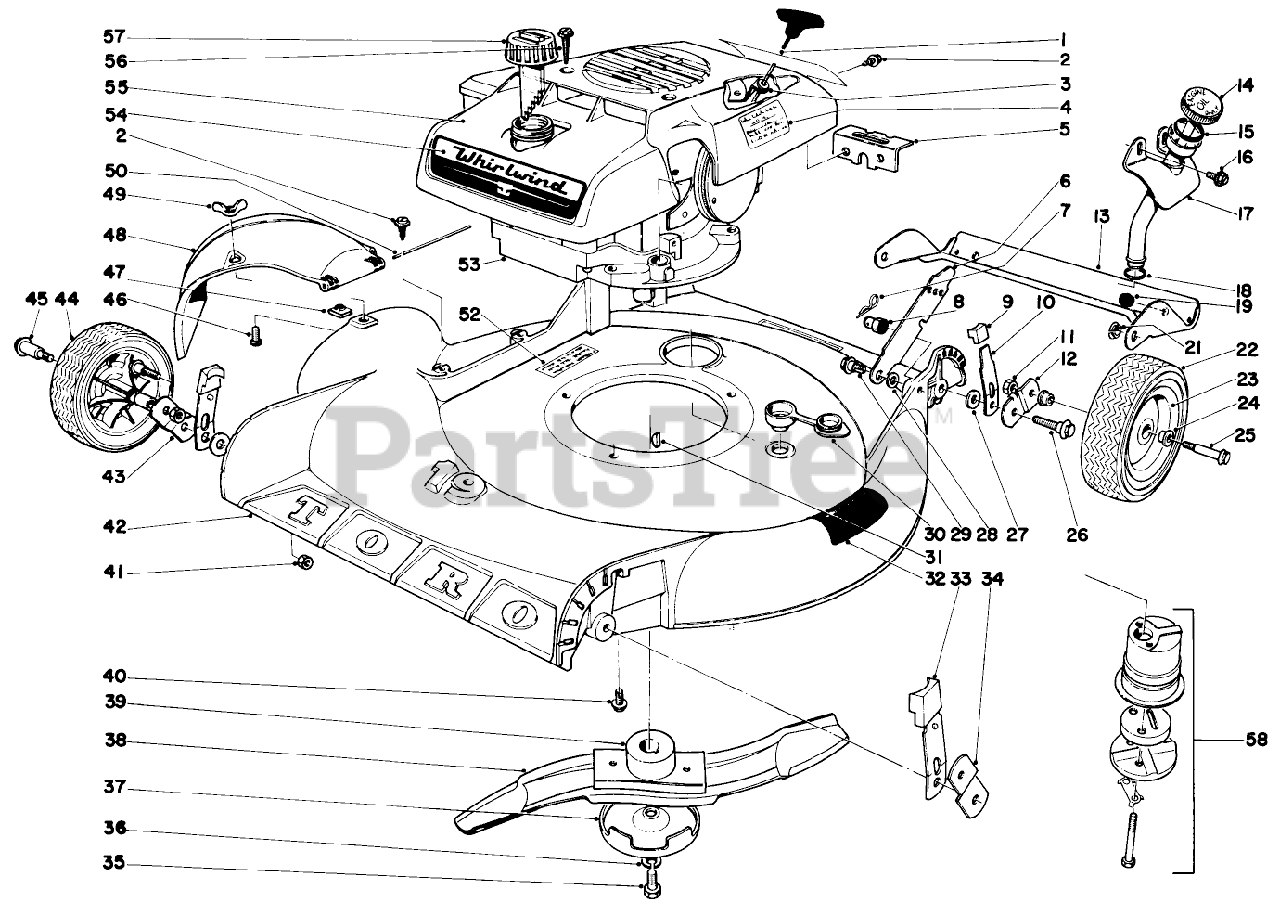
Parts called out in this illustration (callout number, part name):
1	Decal
2	SCREW-HWHTF
3	Bracket,Recoil
4	Decal,Start
5	Bracket
6	Latch
7	PIN-COTTER, HAIR
8	Nut
10	Spring Arm
11	Nut
12	Pivot Arm
13	REAR SAFETY SHIELD
14	Dipstick
15	O-Ring
17	Oiler Tube
18	O-RING
19	SKID BUTTON
21	Nyliner
22	8 TIRE
23	Wheel Assy. (Incl. Ref. #24)
24	Bushing
25	Wheel Bolt
26	Pivot Screw
27	WASHER-PIVOT
28	SPACER
29	SCREW-SHOULDER
30	Washer Plug
31	KEY-WOODRUFF
33	ARM KNOB
34	Pivot Arm
35	SPECIAL SCREW
36	WASHER-LOCK
37	ANTI-SCALP CUP
38	Blade
39	BLADE RETAINER WA
40	Screw
41	Nut
42	Housing
43	Pivot Arm
47	NUT-SPEED
48	Deflector
49	NUT-WING SPECL
50	HINGE PIN
52	Decal
53	Engine, Recoil
54	Decal
55	Shroud
56	SCREW-HWH
57	Gas Cap
58	MUFFLER KIT
